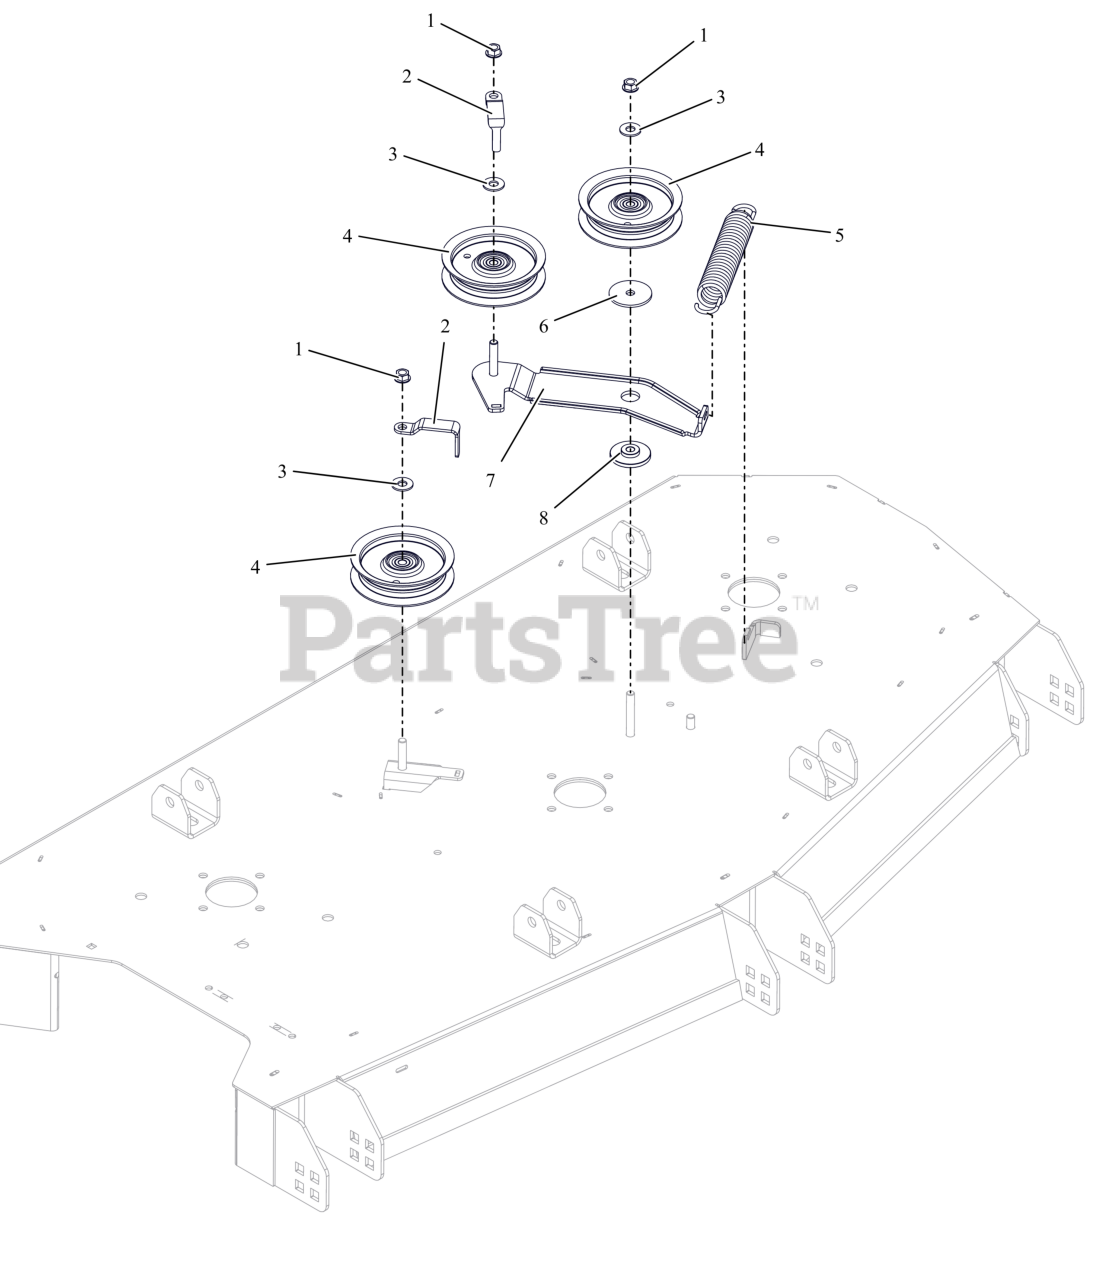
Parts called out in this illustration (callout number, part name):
1	NUT-LK-CTR-FLG .375-16 GF ZCC
2	FINGER, BELT (BLACK)
3	WSHR,FLT .438X1.00X.083 ZCC
4	IDLER, FLAT - 4.06" X .75"
5	SPRG, EXTENSION .170X1.385X6.7
6	WSHR-FL-STL 0.406X2X0.125 ZCC
7	ARM- TENSIONER
8	BSHG-FLG .406X.88X.43X.25
